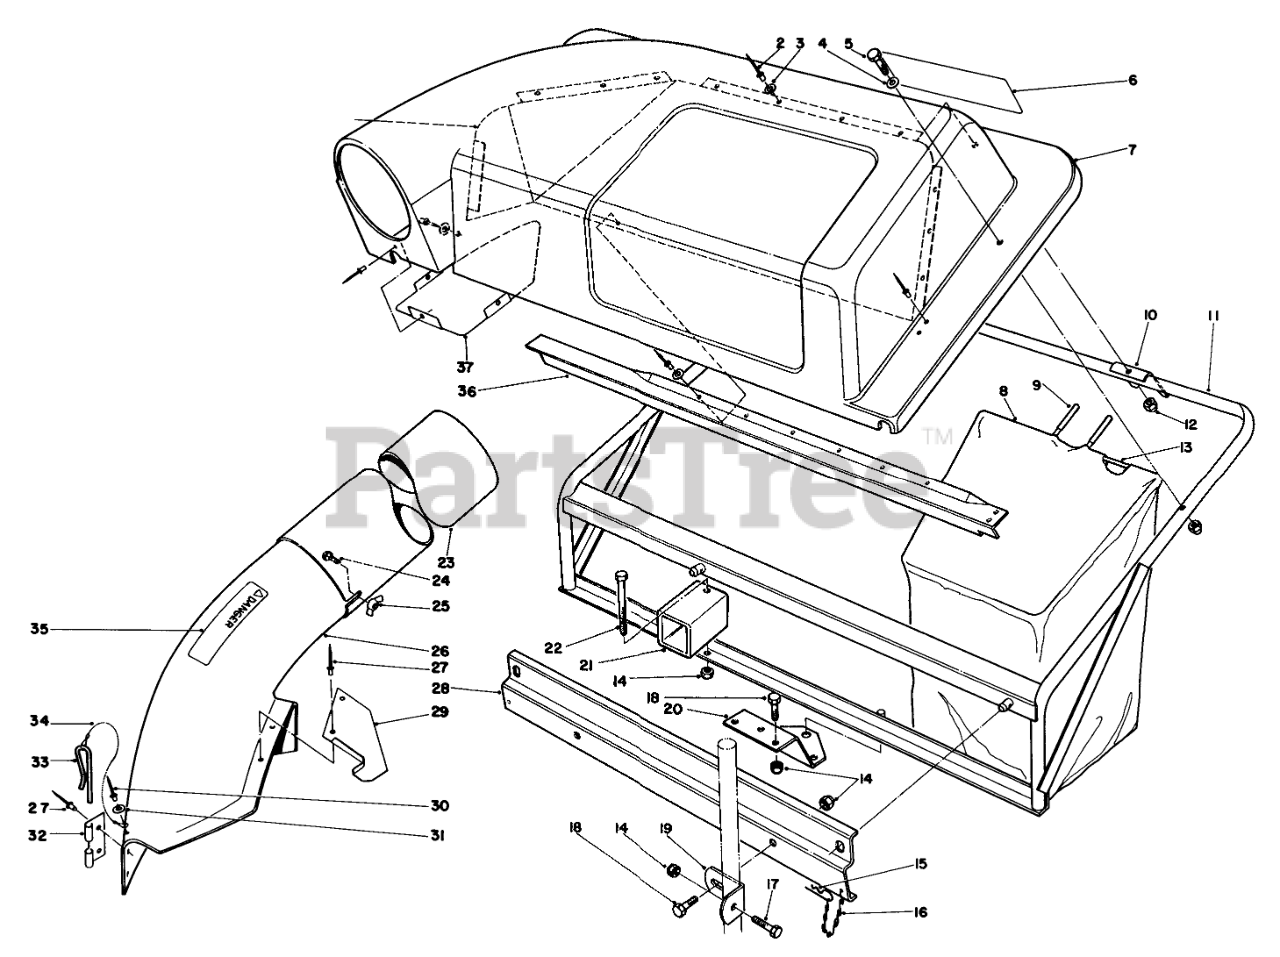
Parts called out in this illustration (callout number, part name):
1	Screen Cover
2	NUT-LOCK
3	WASHER-FLAT
4	WASHER-PLAIN
5	SCREW-HH
6	TWIN BAGGER DECAL
7	Cover
8	Bag-Twin Bagger (Incl. Ref. #9 & 13)
9	GRIP-HANDLE, BAG
10	BAG FRAME BRKT
11	Frame
12	NUT-LOCK, CAP
13	Frame-Bag
14	NUT-LOCK, CONE
15	PIN-HAIR
16	6-LINK CHAIN W/HOOK
17	SCREW-HH
18	SCREW-HH
19	Bracket Mtg. Grass Catcher
20	MTG PLATE B
21	FRAME SUPT TUBE B
22	SCREW-HH
23	TUBE(ROUND&LONG)
24	BOLT-CARR
25	NUT-WING SPECL
26	Chute Assembly (Incl. Ref. #27, 29-35)
27	RIVET-BLIND
28	Bracket Frame Support
29	CHUTE SUPT BRKT
30	RIVET-BLIND
31	WASHER-PLAIN
32	BRACKET-MOUNTING, CHUTE
33	PIN-LOCKING, CHUTE
34	LANYARD
35	Decal-Chute
36	SCREEN SUPT BRKT B
37	Shield Cover
